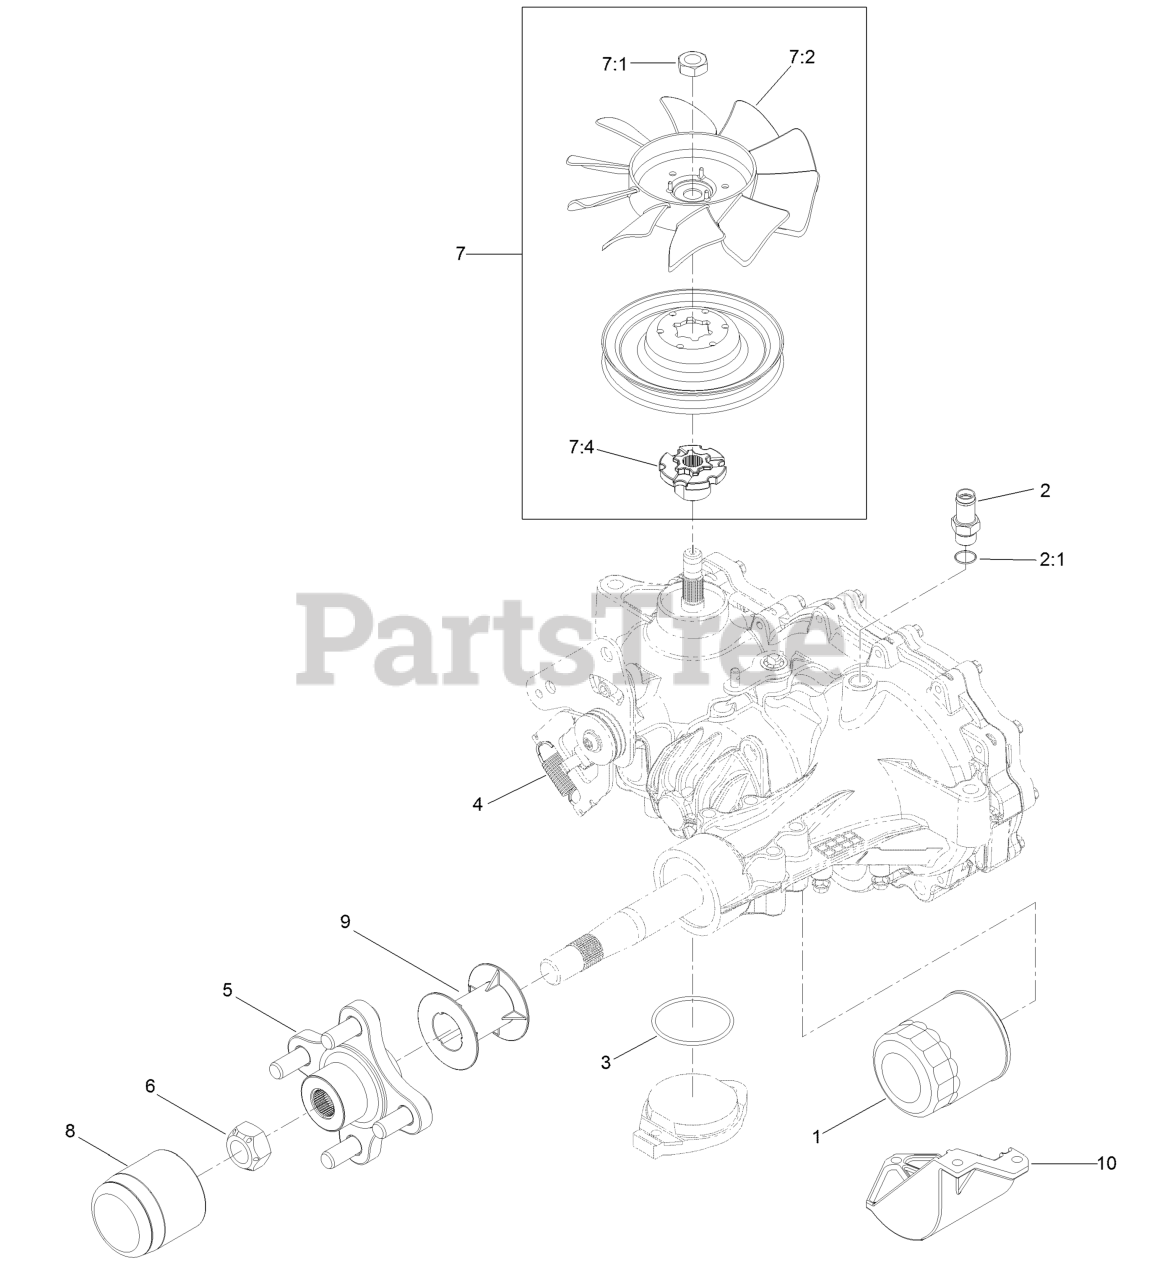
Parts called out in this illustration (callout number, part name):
1	Filter-Hydraulic
2	Adapter-Straight
2:1	O-Ring
3	O-Ring-Charge Seal Cover
5	Hub-Offset
6	Nut-Hub
7	Fan And Pulley Kit
7:4	Hub-Pulley
8	Cap-Axle, Long
9	Tube-Axle
10	Guard-Filter, LH
99	Seal Kit
99	Brake Shaft Seal Kit
